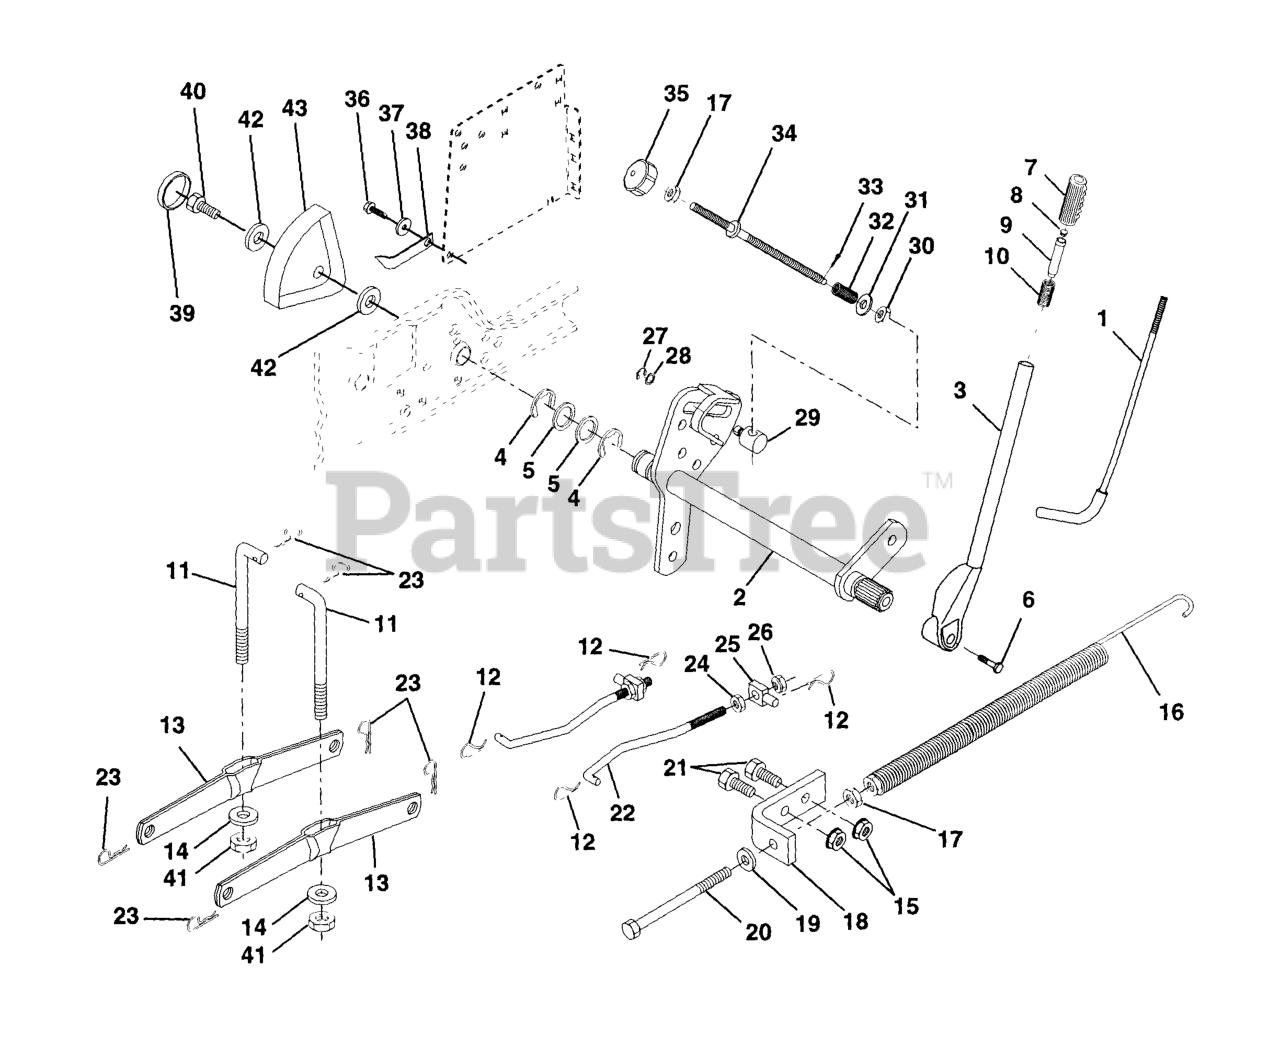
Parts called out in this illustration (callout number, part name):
1	LEVER ROD LT
2	SHAFT ASM, LIFT VGT
3	LIFT LEVER KIT
5	Washer 29/32 x 1-1/4 x 16 Ga.
6	BOLT
7	GRIP HANDLE
8	PLUNGER BUT KIT
9	PLUNGER BUT KIT
10	SPRING**
11	LINK LIFT
12	SPRING RETAINER
13	ARM.REAR.SUSPENSION
14	BEARING PIVOT
16	LIFT SPRING
17	NUT
19	WASHER
21	BOLT
22	FRONT LINK
23	RETAINER-SPRNG RB
24	NUT.HEX.JAM.1/2-13
25	TRUNION
26	NUT.LK.W/WSH.1/2.
27	Ring, Klip #T5304-37
28	Washer 15/32 x 3/4 x 16 Ga.
29	TRUNION LT
32	SPRING.COMP.INF.H
33	COTTER PIN
34	ROD.LIFT.ADJUSTABLE
35	KNOB INF 3/8-16
36	SCREW
38	POINTER HGT
40	SCREW.THDROL.5/16-18X3/4.TTY
41	NUT CROWNLOCK 3/8-24
43	HEIGHT INDICATOR
